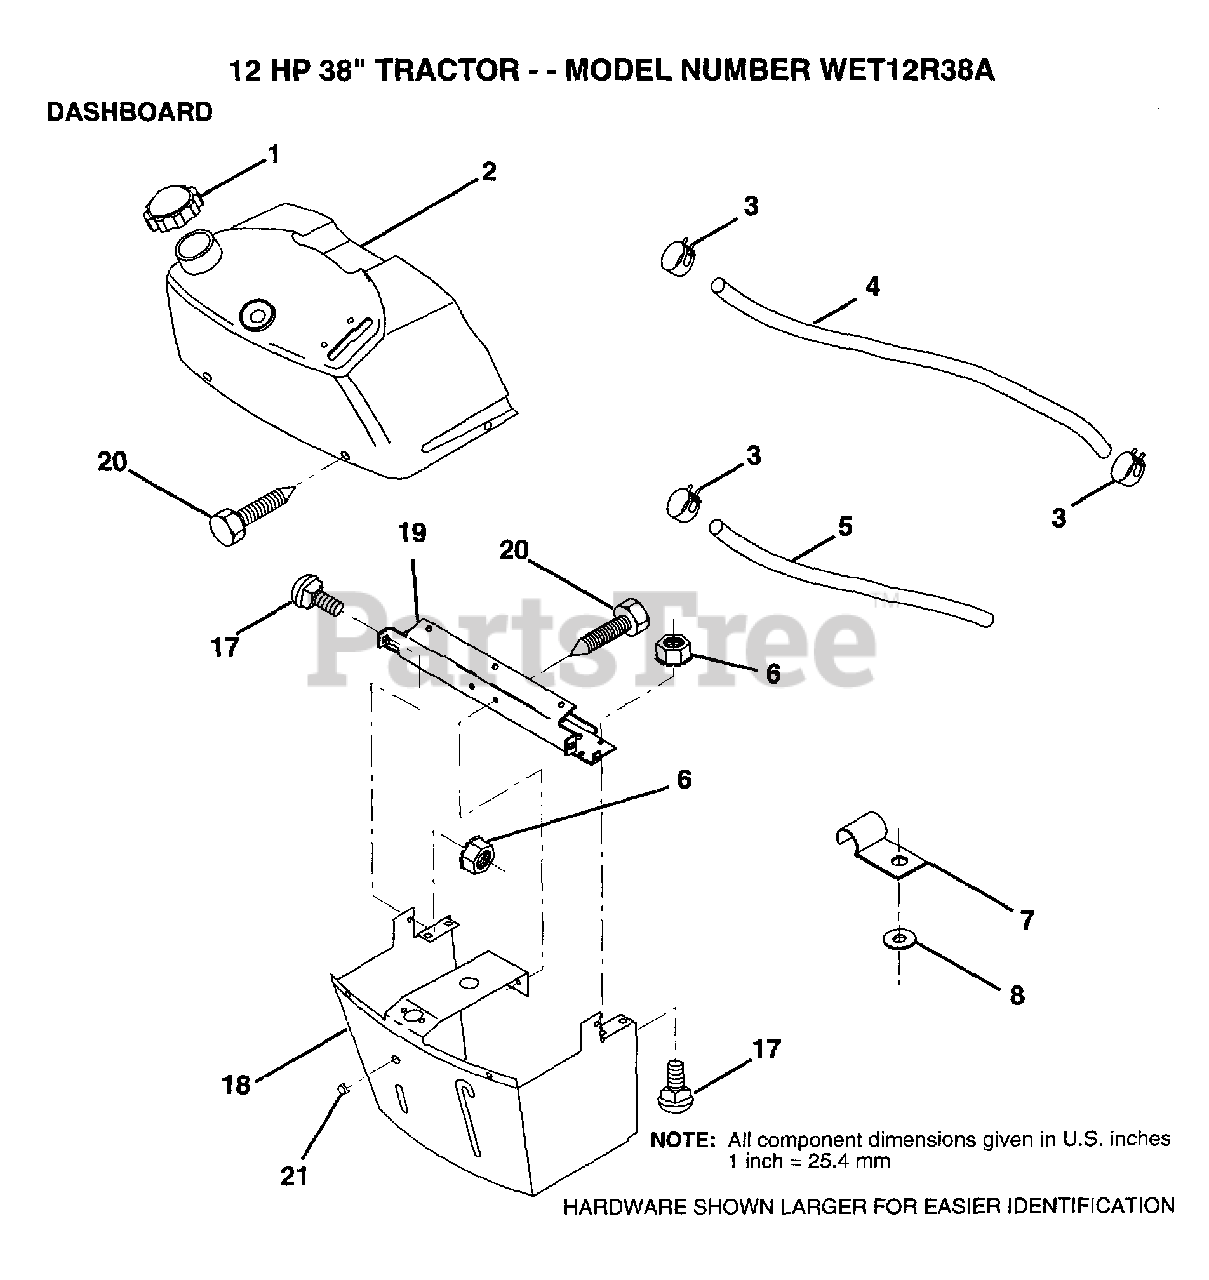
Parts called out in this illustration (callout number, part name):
1	CAP.FUEL.N/VENT
2	TANK.ASM.DASH.LR
3	HOSE CLAMP
5	FUEL LINE T
6	NUT
7	CLIP T
8	WASHER PM
17	BOLT
18	SUPT ASM DASH
19	CROSS BRACE
20	SCREW.1/4-20X1/2
21	PLUG DOME
